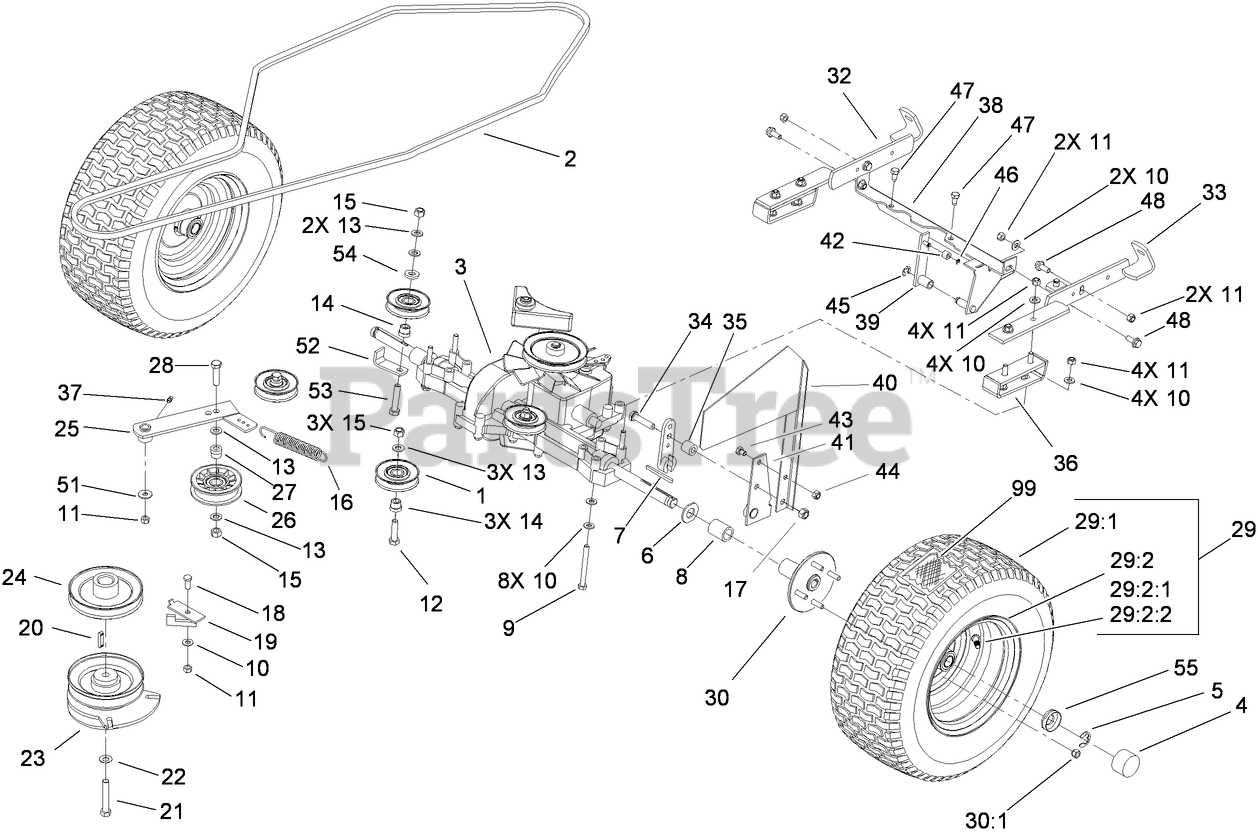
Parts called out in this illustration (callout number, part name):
1	PULLEY-IDLER
2	V-BELT-TRACTION
3	TRANSMISSION
4	CAP-HUB
5	CLIP-SPRING
6	WASHER
7	KEY-SQUARE
8	SPACER-AXLE
9	SCREW-HH
10	WASHER-PLAIN
11	NUT-LOCK, NI
12	SCREW-HH
13	WASHER-FLAT
14	BUSHING-IDLER
15	NUT-LOCK, NI
16	SPRING
17	NUT-LOCK, NI
18	SCREW-HH
19	RETAINER
20	KEY-SQUARE
21	SCREW-HH
22	WASHER-SPRING, BELLEVILLE
23	CLUTCH-ELECTRIC
24	PULLEY-ENGINE
25	ARM-IDLER
26	PULLEY-IDLER
27	BUSHING-IDLER
28	SCREW-HH
29	TIRE AND WHEEL ASM
29:2	WHEEL ASM
29:2:1	Loose Parts Package
29:2:2	Valve-Tire
30	HUB-WHEEL
30:1	NUT-LUG
32	Bracket-Right
33	Bracket-Left
34	SCREW-HH
35	SLEEVE
36	Plate-Reinforcing
37	FITTING-GREASE
38	Bar ASM
40	ARM-CONTROL, CRUISE
42	Roller
43	SCREW-HH
44	NUT-LOCK, NI
45	Stirrup
46	STIRRUP
47	SCREW-THREAD FORMING
48	SCREW-HEX
51	WASHER-PLAIN
52	RETAINER-BELT
53	SCREW-HH
54	WASHER-FLAT
55	RETAINER-CAP, HUB
